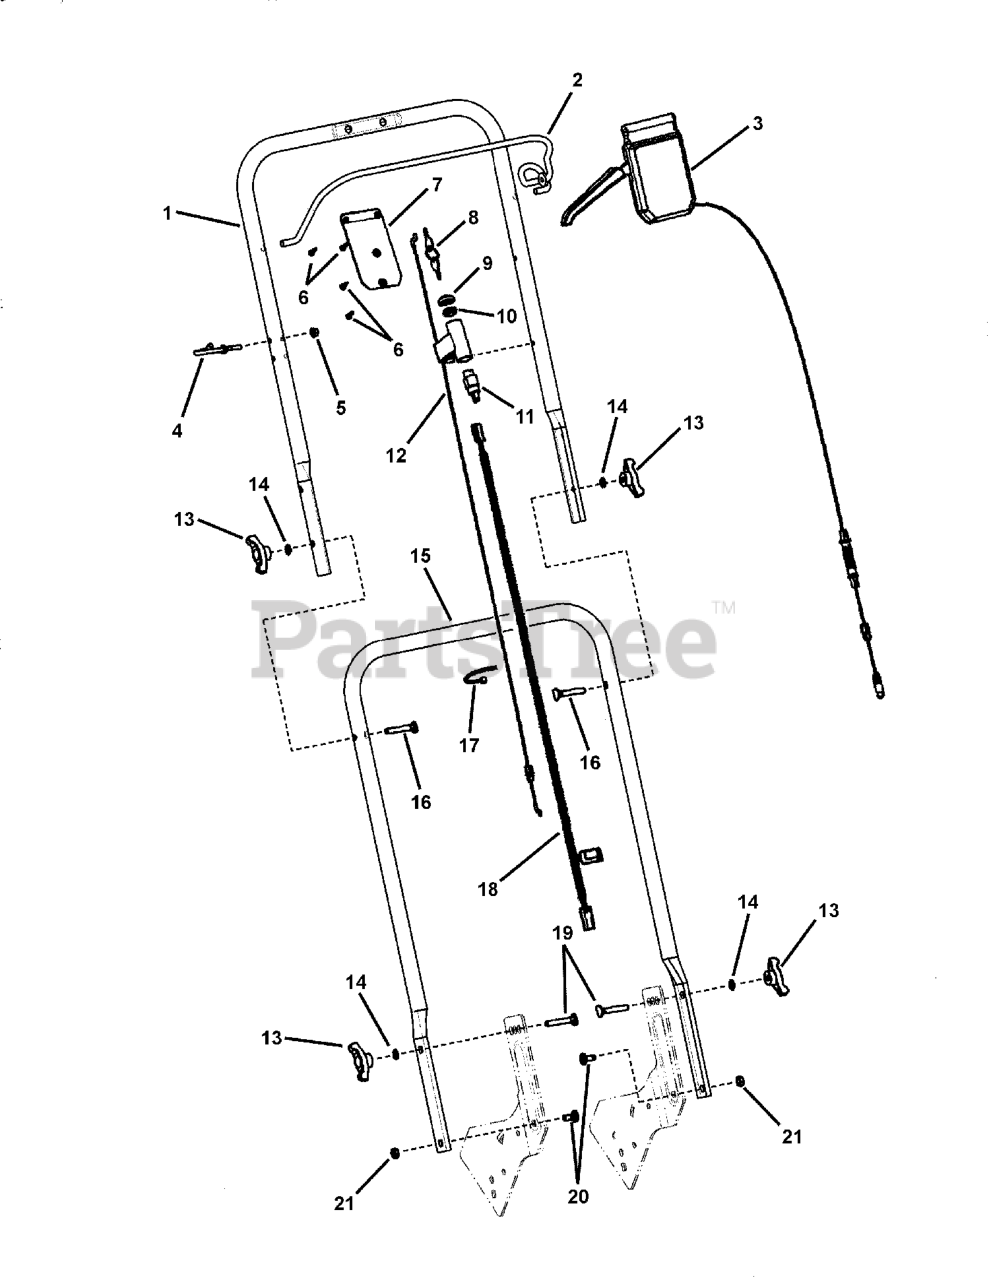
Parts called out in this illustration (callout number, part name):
1	HANDLE, Upper, Flat
2	BAIL, Operator Presence Control
3	ASSY, Control Head, VS, Brute 22"
4	GUIDE, Rope (1/4-20 thread)
5	NUT,1/4-20 Hex Nyloc
6	SCREW, #8-16 Recessed Pan Head (Torxplus)
7	PLATE, Control Panel
8	IGNITION KEY (Pair)
9	CAP, E-Start
10	NUT, 5/8-32, E-Start
11	IGNITION SWITCH, E/S (Start/Run)
12	CABLE, Bail, 22", WBM, Brute, E/S
13	KNOB, 5/16-18 Wing Nut
14	WASHER, 5/16" Internal Tooth Lock
15	HANDLE, Lower Murray, MY09"
16	BOLT, 5/16-18 x 2" Curved Head Square Neck
17	WIRE TIE,11 Inch Std Blk Nylon
18	WIRING HARNESS, RD, 21"/22" WBM
19	BOLT, 5/16-18 x 1" Round Head Square Neck
20	BOLT, 5/16-18 x 5/8" Round Head Square Neck, GR 5
21	NUT, 5/16-18 Hex Large Flange Center Lock
